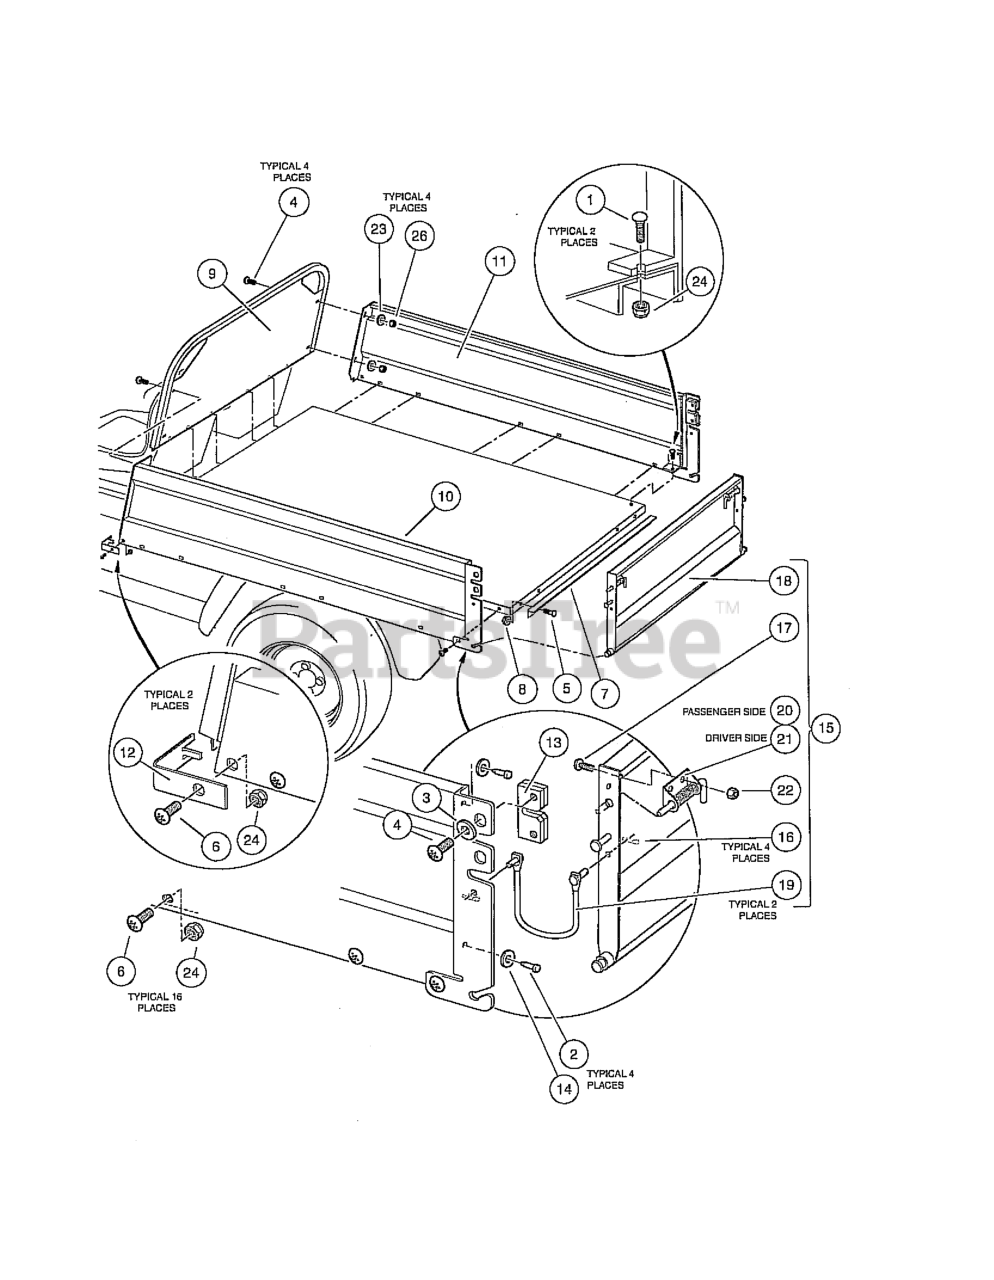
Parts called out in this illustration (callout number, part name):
1	BOLT, 5/16-18 X 1.00 SQ.NECK
2	RUBBER BUMPER
6	SCREW, 5/16-18 X .88 TRX TRUSS
7	BOX BED TAILGATE ANGLE
8	LOCKNUT, 5/16-18 HEX FLANGE
9	FRONT PANEL WELDMENT
10	LEFT PANEL WELDMENT
11	RIGHT PANEL WELDMENT
12	FRONT CORNER CAP
13	SLAM LATCH
14	WASHER, RUBBER 3/8
16	HAIR PIN CLIP
19	TETHER ASSEMBLY
20	SPRING LATCH RIGHT
21	SPRING LATCH LEFT
22	LOCKNUT, 1/4-20 NYLON INSERT
23	WASHER 1/4 FLAT
24	LOCKNUT, 5/16-18 NYLON INSERT
25	LOCKNUT, 1/4-20 NYLON INSERT
